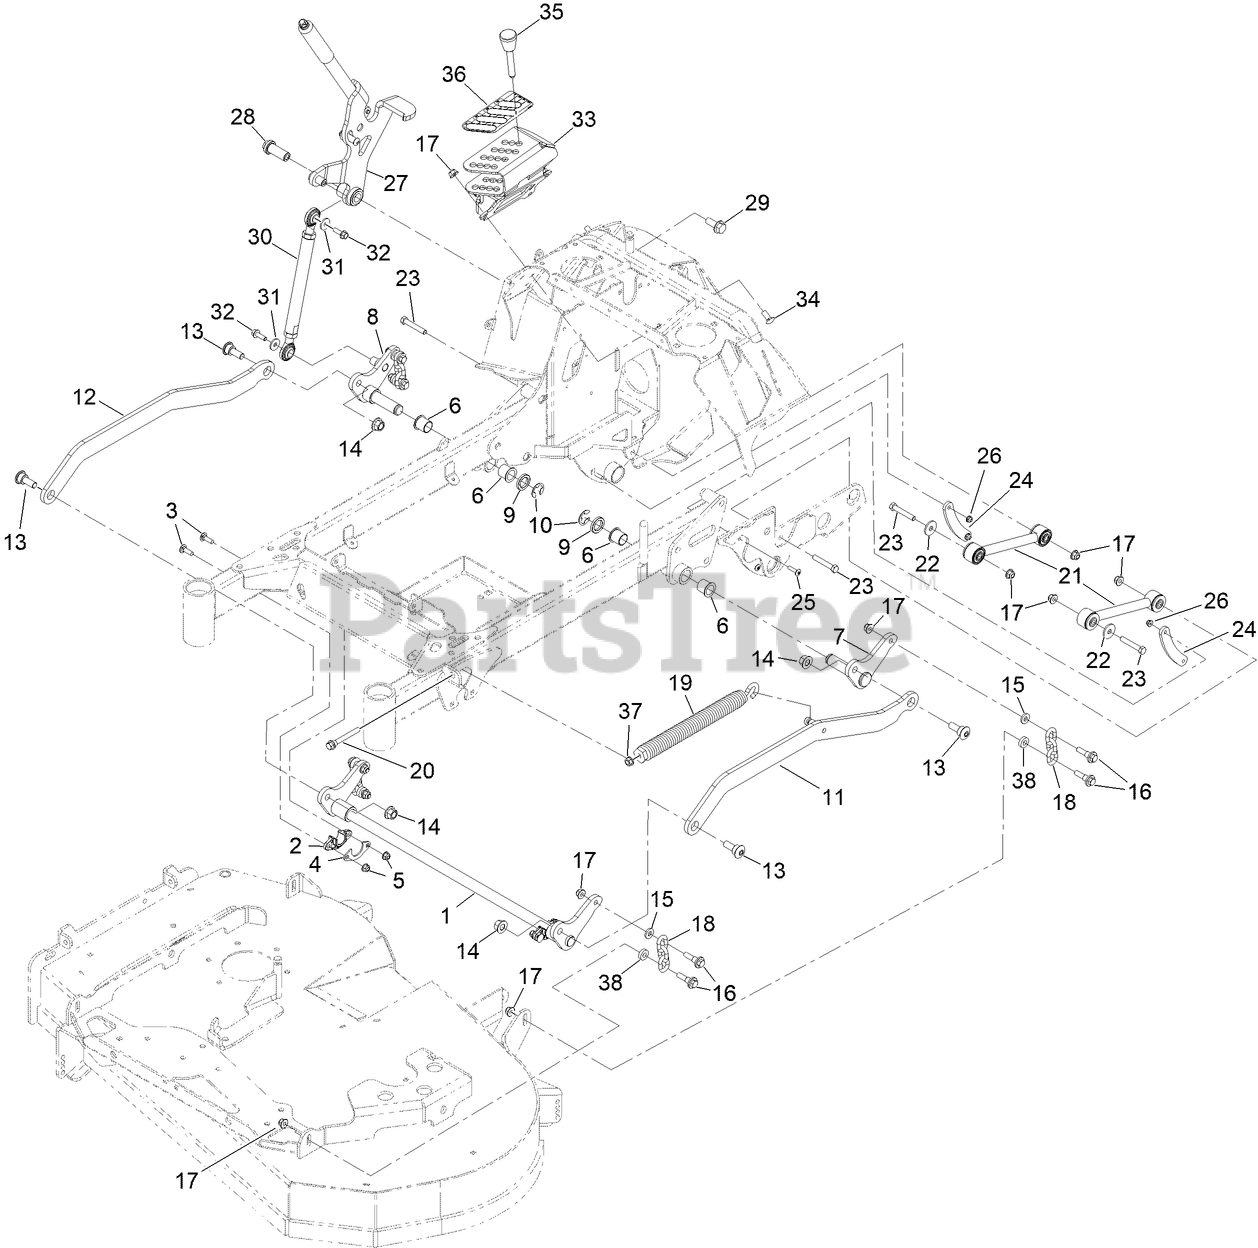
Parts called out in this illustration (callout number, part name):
1	WELD, HOC LIFT SHAFT
2	BEARING-FLANGE
3	BOLT-CARR
4	GUSSET-LIFT, DECK
5	NUT-HF, NI
6	BUSHING, IGUS
7	WELD, BELLCRANK, LT RR
8	WELD, BELLCRANK, RT RR
9	SPACER, HOC PIVOT
10	RING-RETAINING, EXT
11	WELD, LIFT STRAP, LT
12	STRAP, LIFT RT
13	BOLT, SHOULDER
14	NUT-LOCK
15	SPACER
16	BOLT-SHOULDER
17	NUT-HF, NI
18	CHAIN-DECKLIFT
19	SPRING-EXTENSION
20	BOLT-SHOULDER
21	ASM, STRUT W/ BUSHINGS
22	WASHER
23	SCREW-HH
24	STRIP, RUB
25	SCREW-TTH
26	NUT-HF
27	ASM, HOC LEVER
28	PIVOT, HOC LEVER
29	SCREW-HHF
30	ASM, LIFT ROD
31	WASHER-FRICTION
32	SCREW-HHF
33	WELD, HOC INDEX
34	SCREW-CARR
35	PIN-HOC
36	DECAL-HEIGHT OF CUT
37	NUT-HHF, WHIZ
38	SPACER
